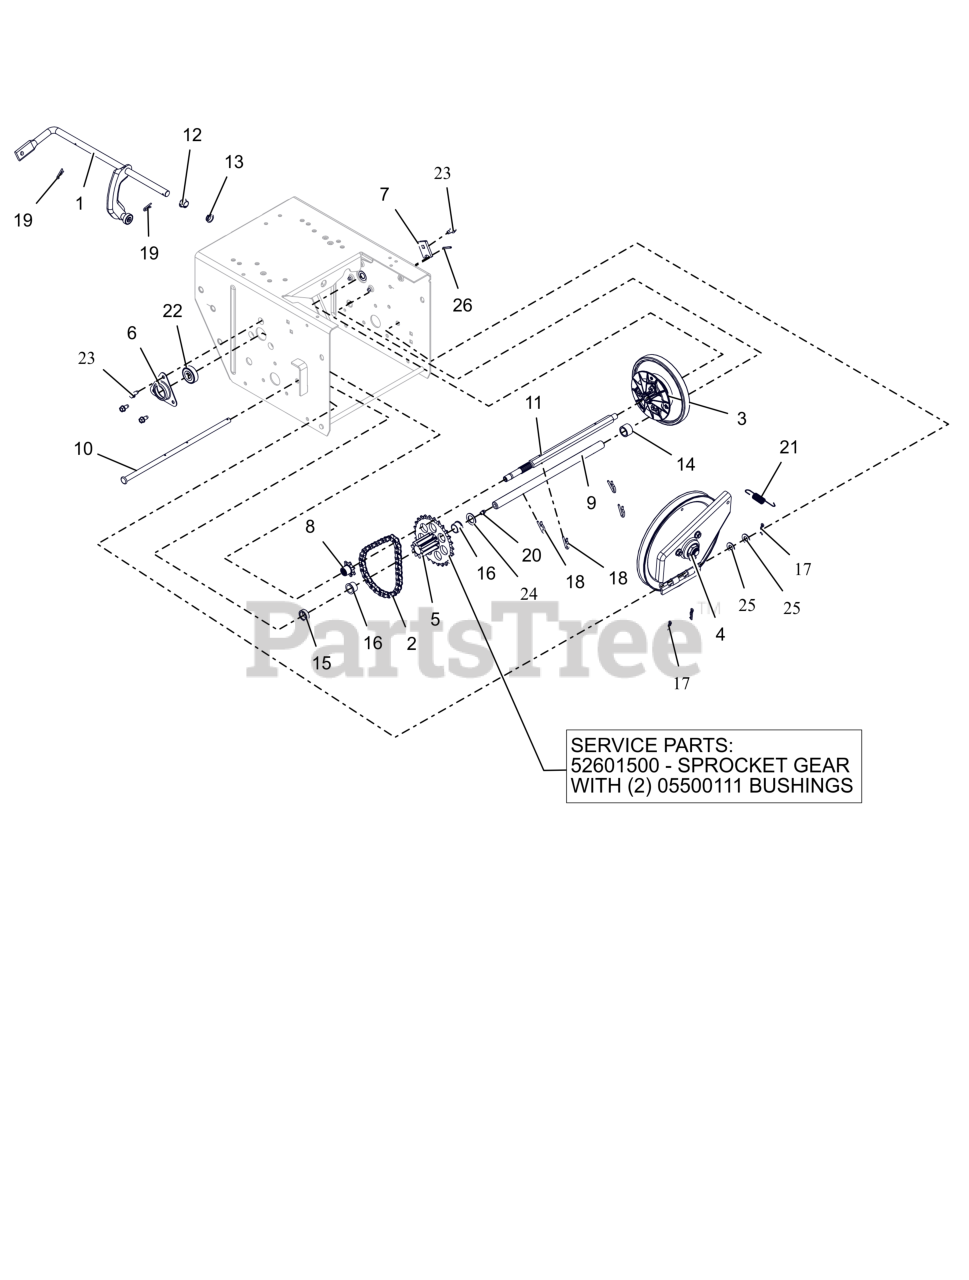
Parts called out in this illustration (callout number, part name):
1	ARM, SHIFT-PRO (ASSEMBLY)
2	CHAIN - #41, 32 PITCHES
3	DISC, FRICTION DRIVE-ASSEMBLY
4	PLATE, SWING ASSEMBLY-DEEP
5	PINION & SPROCKET
6	FLANGE, BEARING
7	TAB, ANTI ROTATION
8	SPROCKET, PINION 7T W/SPLINE
9	SHAFT, PINION - HARDENED
10	PIN, PIVOT
11	SHAFT, HEX - HEAT TREATED
12	BUSHING, POLYLINER-.50 SPLIT
13	BUSHING, POLYLINER-.50 SNAPIN
14	SPACER, .635X.880X.611
15	BSHG-SLV, .635X.880X.305
16	BSHG-FLG .625X.750X.500X.875
17	PIN, HAIR #225 .072X1.09
18	PIN, SPRING CLIP
19	CLIP, SPRING
20	ZERK,FITTING .25X.125 DRIVE IN
21	SG-TENS .048X.50X2.8
22	BRG-BALL .437X1.375X.437
23	SCR-TAP .25-20X.50 HWH ZCC
24	WSHR, FLT .630X1.005X.062 ZCC
25	WSHR,FLT .406X.812X.065 ZCC
26	PIN-ROLL .125X1.00
